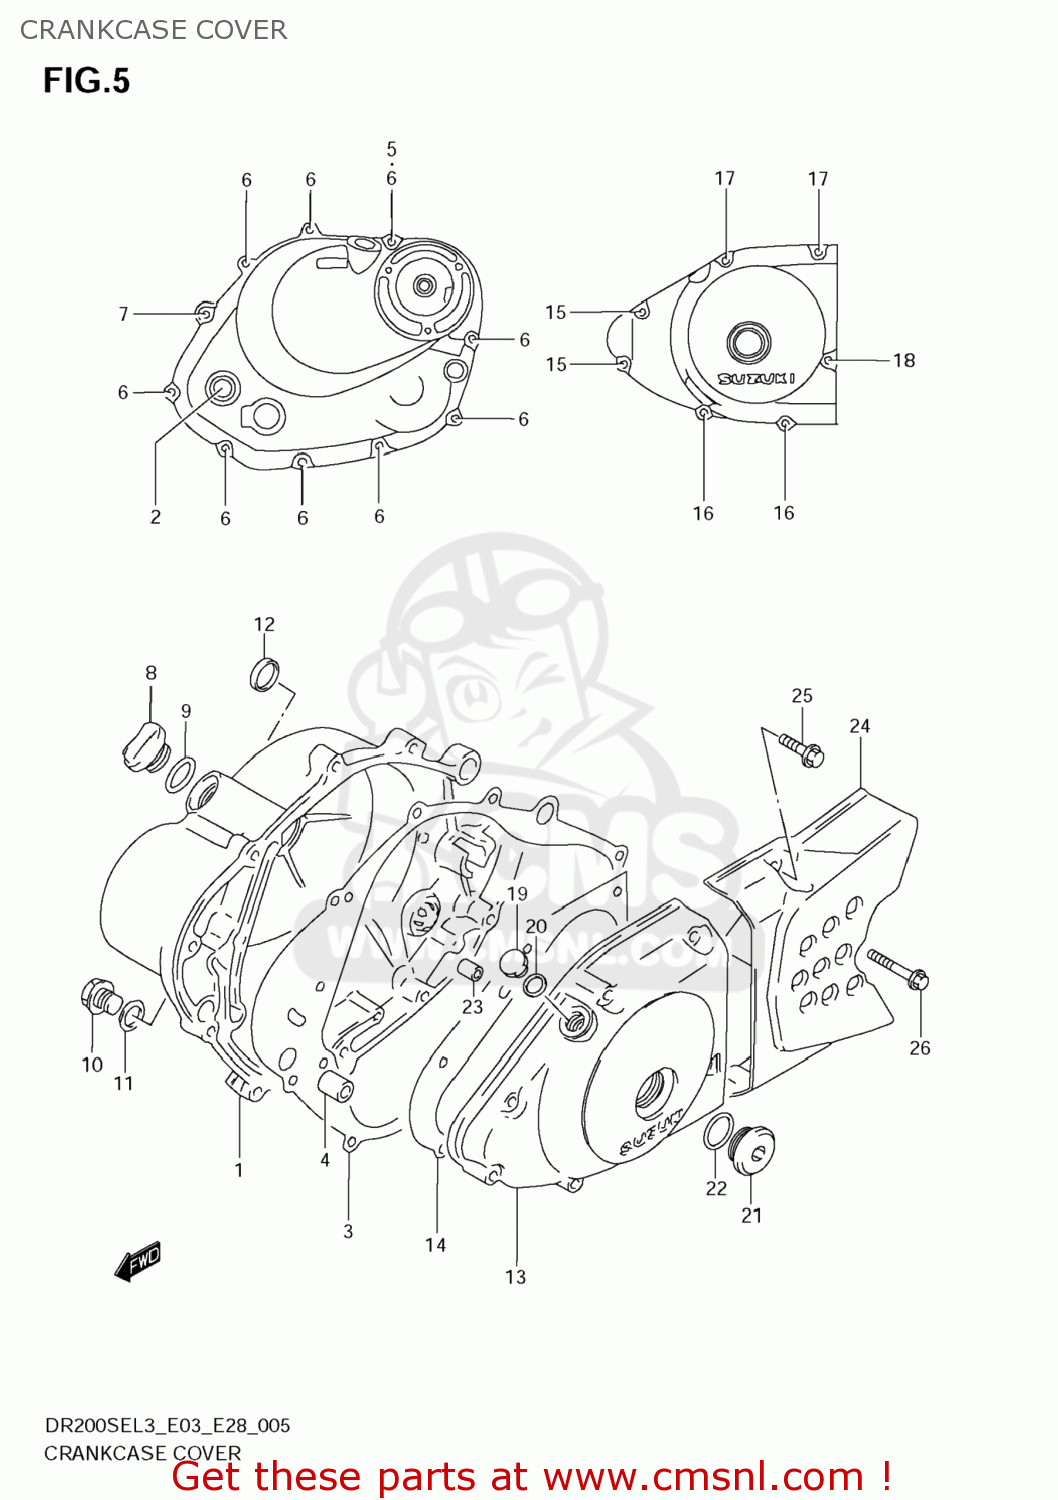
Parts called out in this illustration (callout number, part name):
1	COVER,CLUTCH
2	LENS,OIL LEVEL CHECK
3	GASKET,CLUTCH COVER (NAS)
4	PIN
5	GASKET(5.8X13X1.2) (NAS)
6	BOLT
7	BOLT
8	PLUG
9	O RING(D:3.1,ID:16.8)
10	PLUG(14X12)
11	GASKET(13.8X18.8X4.8) (NAS)
12	PLUG,CLUTCH COVER KICK
13	COVER,MAGNETO
14	GASKET,MAGNETO COVER (NAS)
15	BOLT
16	BOLT
17	BOLT
18	BOLT
19	PLUG,12X9
20	GASKET(12.1X16.2X3.7) (NAS)
21	PLUG(26X9)
22	O RING(D:3.1,ID:22.7)
23	PIN
24	COVER,ENGINE SPROCKET
25	BOLT
26	BOLT
